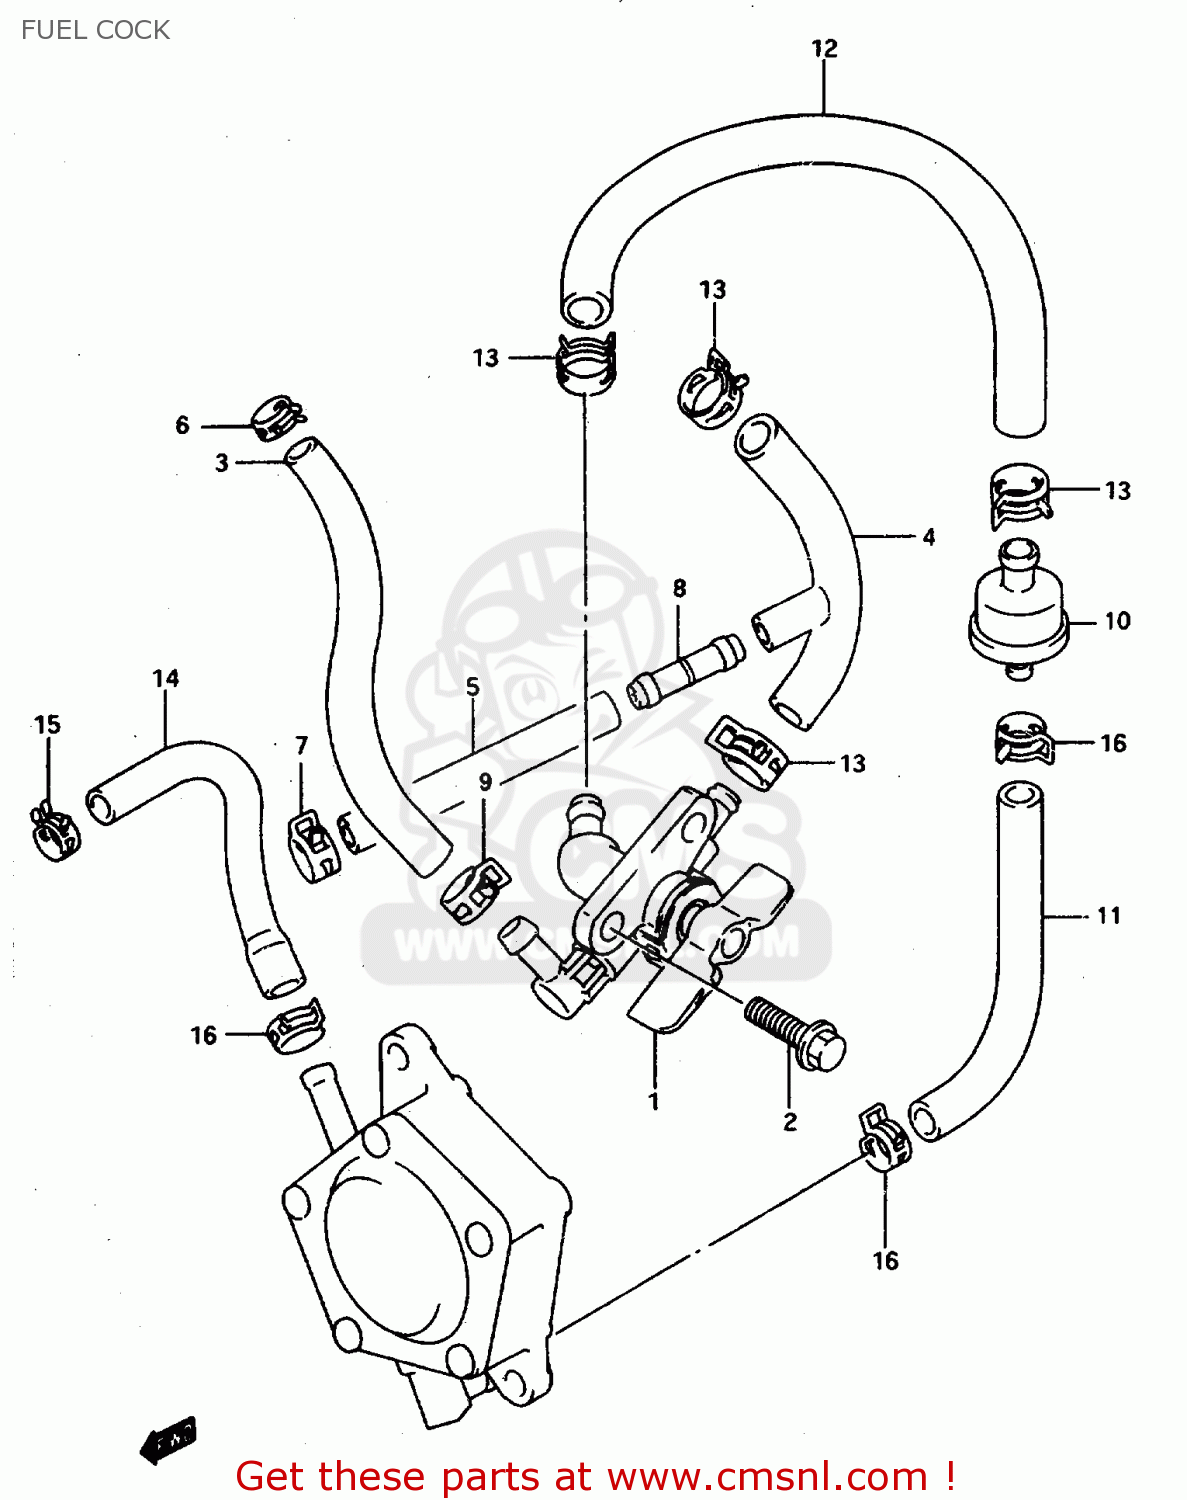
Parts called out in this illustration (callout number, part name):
1	COCK ASSY,FUEL
2	BOLT MAGNETO S
3	HOSE
4	HOSE,FUEL RESERVE
5	HOSE (5.3X10.5X600)
6	CLIP
7	CLIP
8	UNION
9	CLIP
10	FILTER,FUEL
11	HOSE (5.3X10.5X600)
12	HOSE(7X12X600)
13	CLIP
14	HOSE
15	CLIP
16	CLIP
